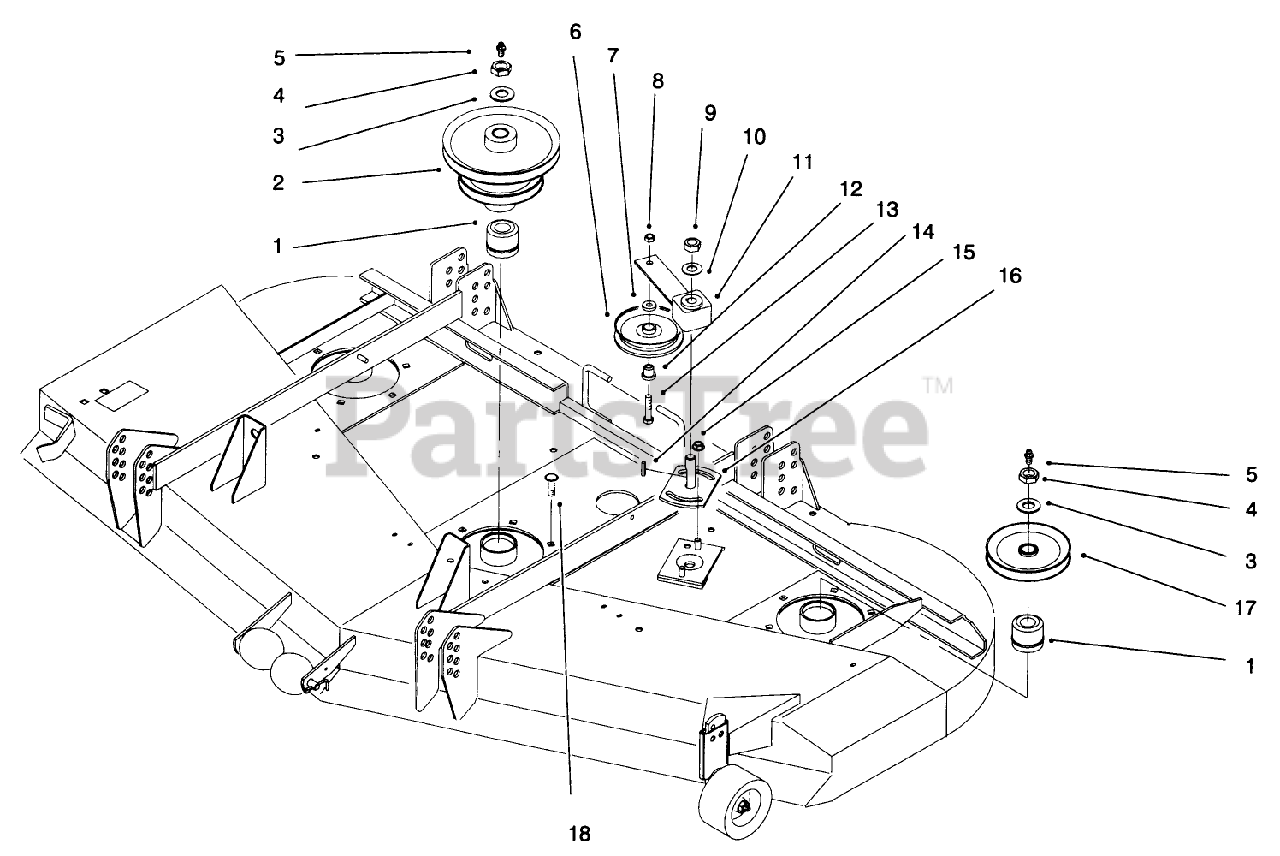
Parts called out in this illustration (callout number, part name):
1	BEARING ASM
2	PULLEY & HUB WA B
3	WASHER
4	NUT-HEX
5	FITTING-GREASE
6	PULLEY-IDLER
7	WASHER-FLAT
8	NUT-HEX
9	NUT-LOCK NI
10	WASHER-FLAT
11	IDLER ARM ASM
12	BUSHING-PULLEY
13	SCREW-HH
14	KEY-SQUARE
15	NUT-HHF, WHIZ
16	PLATE-IDLER, LH
17	PULLEY AND HUB ASM
18	SCREW-CARR
